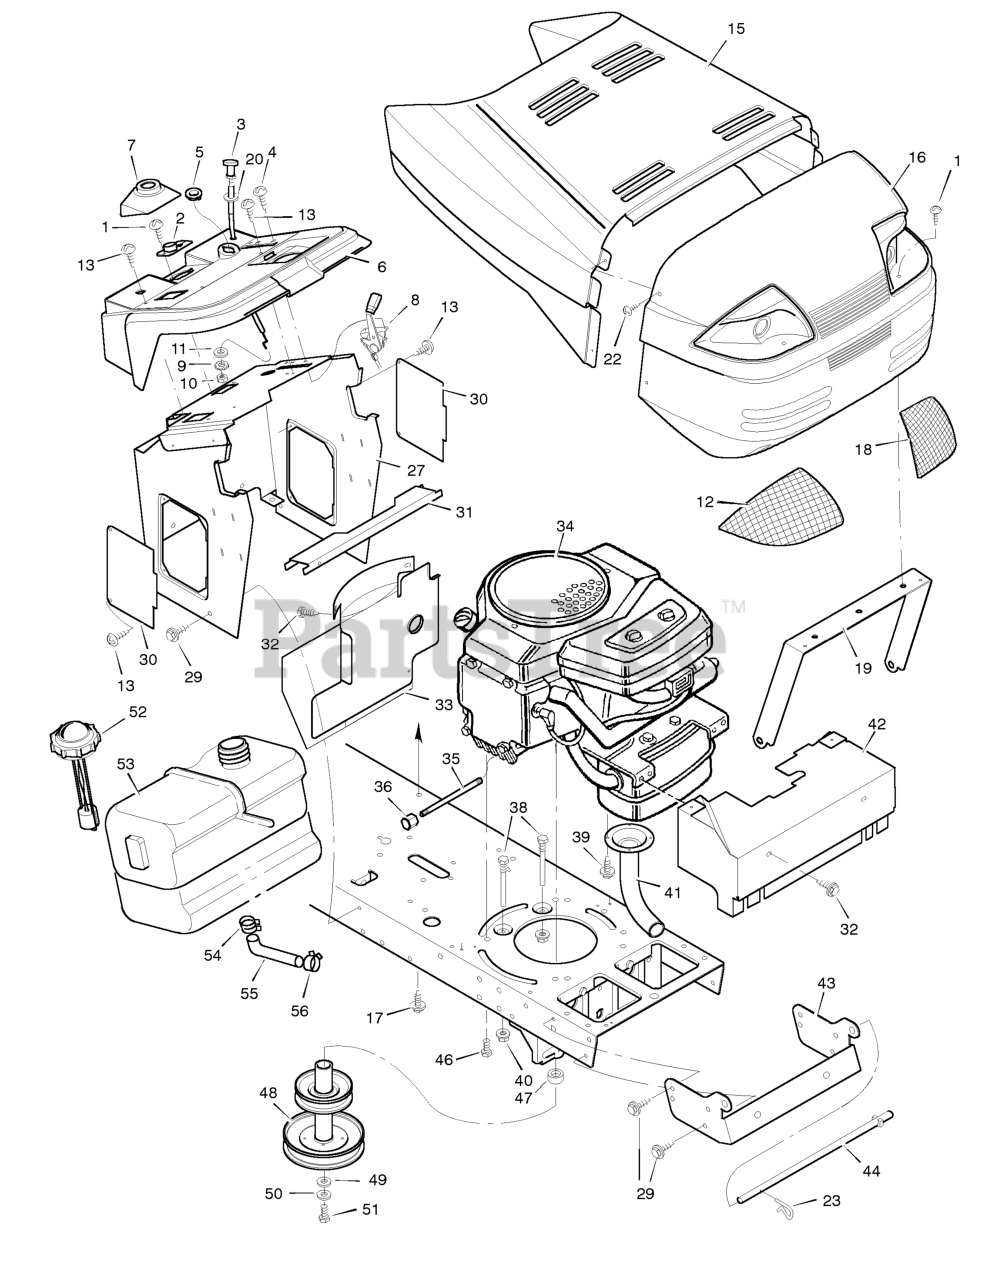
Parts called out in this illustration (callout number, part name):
2	Bearing, Steering Post
3	Cable, Choke
5	Bushing
7	Support, Bellows
8	Throttle Control
9	Lockwasher
10	Nut, Hex
12	Lens, Right
13	Screw
15	Hood
16	Grille - Gray
18	Lens, Left
19	Brace, Grille
20	Washer
23	Pin, Hair
27	Console Assembly
30	Panel, Side Access
31	Support, Fuel Tank
32	Screw
33	Baffle, Rear Heat
34	Engine *
35	Oil Drain Extension
36	Oil Drain Cap
38	Guide, Belt
40	Locknut, Flange
41	Pipe, Exhaust
42	Shield, Heat
43	Support, Grille
44	Rod, Pivot
46	Bolt, Hex
47	Spacer, Engine
48	Pulley Assembly, Stack
50	Lockwasher
51	Bolt, Hex
52	Cap, Fuel
53	Fuel Tank
54	Clamp, Hose
55	Fuel Line
56	Clamp, Hose
